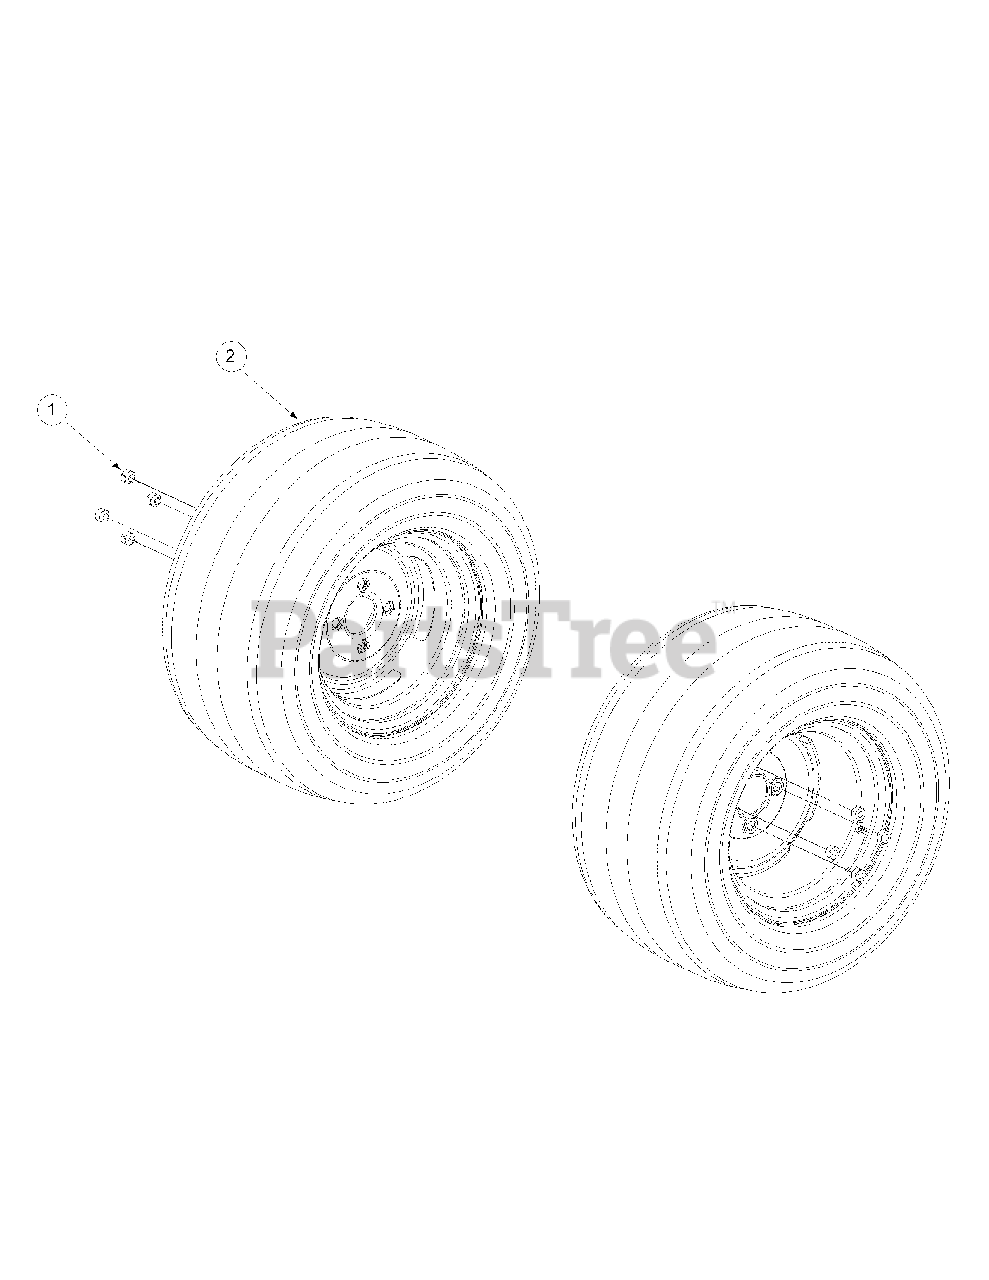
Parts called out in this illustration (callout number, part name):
1	Lug Nut, 1/2-20
2	Wheel Assembly, 24 x 12.00-12, Beige includes:
2	Tire, 24 x 12.00-12, Turf Master
2	Rim, 12 Dia x 8.50 width
2	Wheel Assembly, 24 x 12.00-12, Turf Saver
2	Tire, 24 x 12.00-12, Turf Saver
